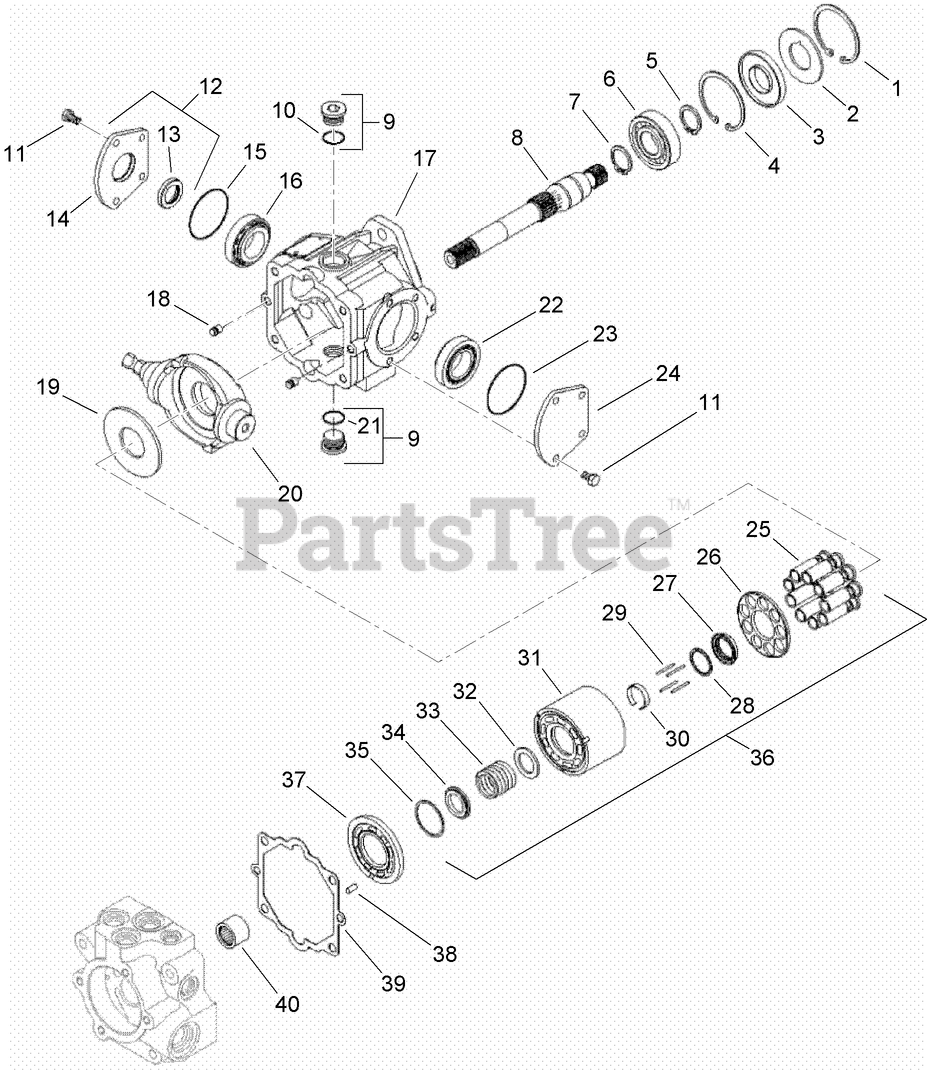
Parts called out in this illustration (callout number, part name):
1	RING-RETAINING, INT
2	WASHER-SUPPORT, SEAL
3	SEAL-BEARING, CARRIER
4	RING - Retainer
5	RING-RETAINING
6	BEARING
7	RING - Retainer
8	SHAFT - Front 15T
9	PLUG-SOCKET HEAD
10	O-RING
11	BOLT - M8 x 16, 10.9 ZND
12	ASSEMBLY - Trunnion Cover
13	SEAL - Lip
15	O-RING
16	KIT - Bearing
17	HOUSING - Variable
18	Pin
19	PLATE-Thrust
20	PLATE - Swash
21	O-RING
22	BEARING ASSY - Cup and Cone
23	RING - 2.612 ID X .094
25	ASSEMBLY - Piston
26	RETAINER - Slipper
27	GUIDE - Slipper Retainer
28	WASHER - Special
29	PIN - Slipper Hold Down
30	RETAINER - Slipper Hold Down Pin
31	BLOCK - Cylinder
32	Washer
33	SPRING - Cylinder Block
34	Washer
35	Ring - Retaining
36	KIT - Cylinder Block
37	PLATE - Valve - RH - CW
39	GASKET - End Cap
40	BEARING-Needle
